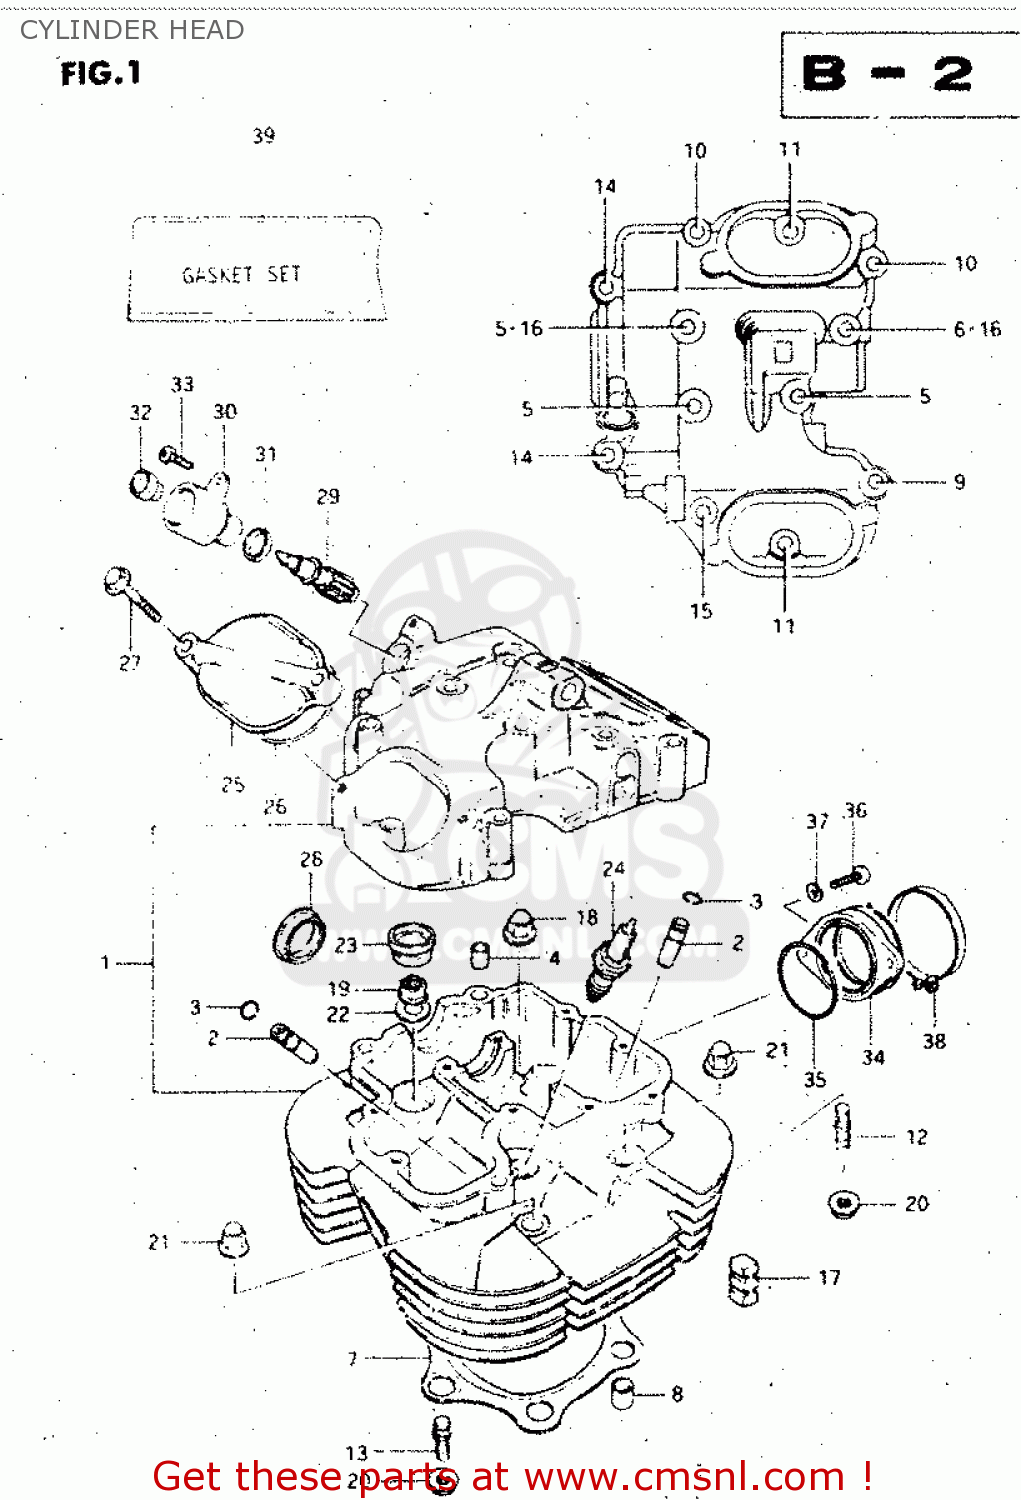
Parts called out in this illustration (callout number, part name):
1	HEAD,CYLINDER (4-VALVE)
2	GUIDE,VALVE
3	RING,SNAP
4	PIN(6.2X8X11)
5	BOLT (6X60)
6	BOLT 6X55
7	GASKET,CYLINDER HEAD (NAS)
8	PIN
9	BOLT 6X50
10	BOLT (6X45)
11	BOLT 6X30
12	STUD
13	STUD
14	BOLT(6X130)
15	BOLT (6X60)
16	WASHER
17	PAD,CYLINDER
18	NUT
19	NUT
20	NUT 8MM
21	NUT
22	GASKET(10.5X22X2) (NAS)
23	NUT,CYLINDER HEAD SEAL
24	SPARK PLUG D8EA
25	CAP,INSPECTION HOLE
26	O RING(D:2.4,ID:23)
27	BOLT
28	PLUG(OD:30)
29	GEAR,TACHOMETER DRIVEN
30	SLEEVE,TACHOMETER DRIVE GEAR
31	SEAL,TACHOMETER DRIVEN
32	SEAL,OIL(5X12X8)
33	SCREW(5X12)
34	PIPE,INTAKE
35	O-RING (D:2.4 ID:45.7)
36	SCREW
37	LOCK WASHER
38	CLAMP
39	GASKET SET
